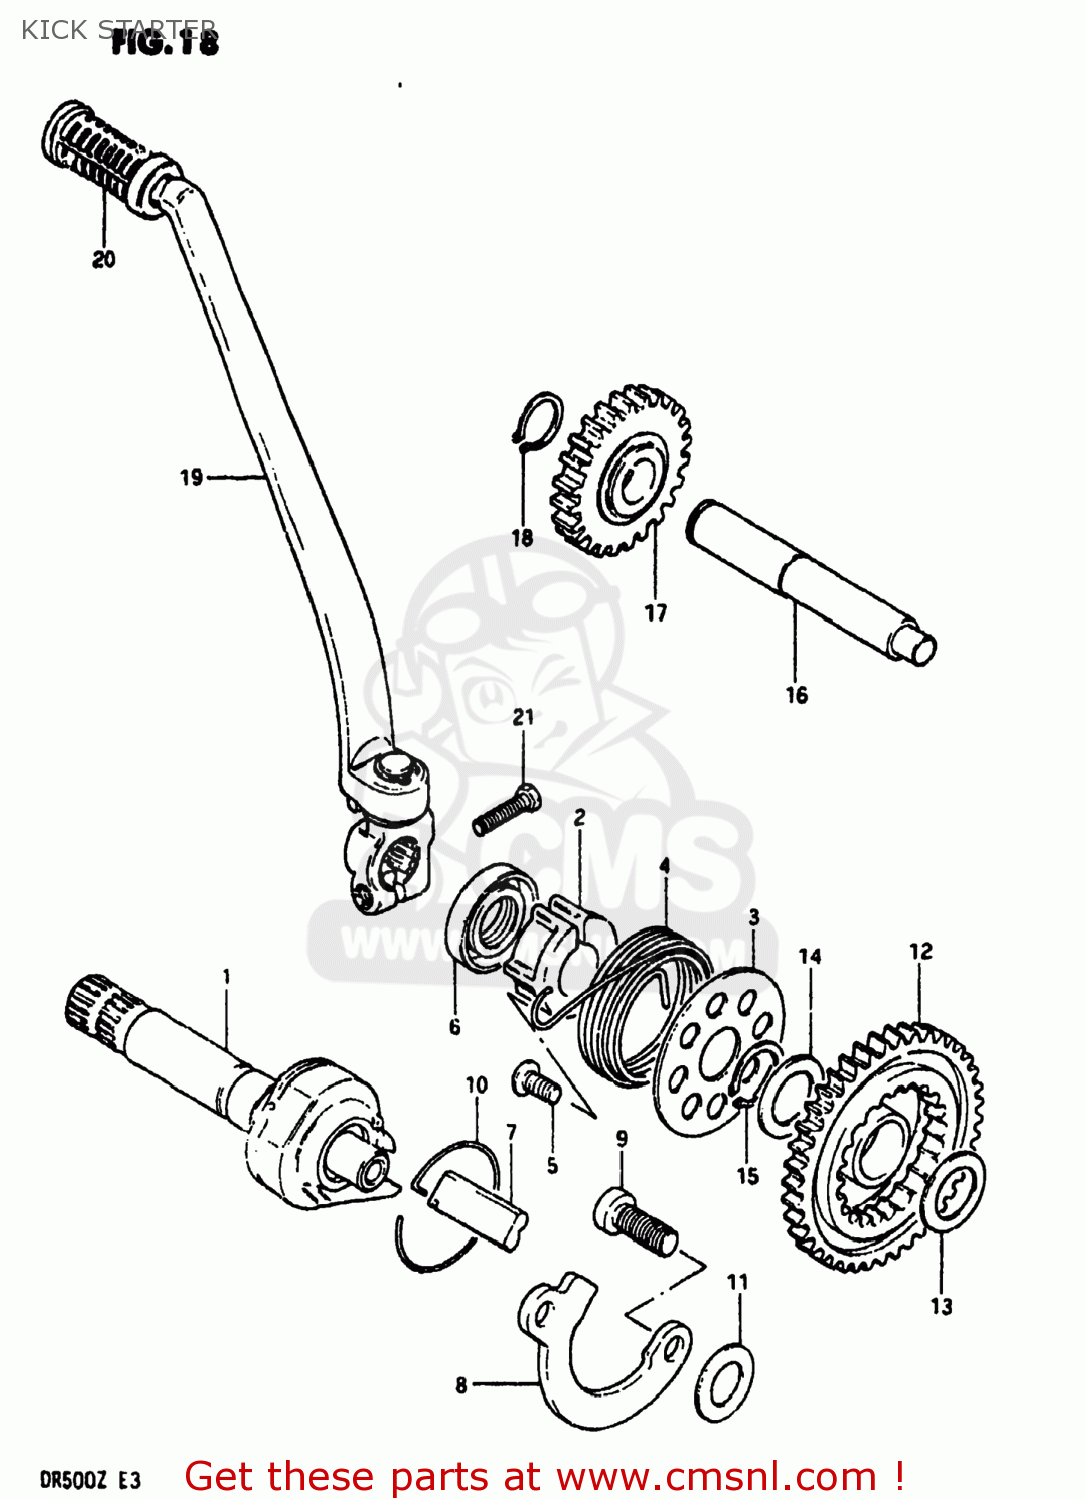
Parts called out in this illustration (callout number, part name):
1	SHAFT,KICK STARTER
2	GUIDE,KICK SHAFT SPRING
3	HOLDER,KICK SHAFT SPRING
4	SPRING
5	SCREW
6	SEAL,OIL(20X37X7)
7	PAWL,KICK STARTER
8	LIFTER,KICK STARTER
9	STOPPER,KICK STARTER
10	SPRING,KICK START PAWL RETURN
11	WASHER
12	GEAR,KICK STARTER DRIIVE
13	WASHER
14	WASHER,THRUST
15	CIRCLIP
16	SHAFT,KICK STARTER IDLE
17	GEAR,KICK STARTER IDLE
18	CIRCLIP
19	LEVER ASSEMBLY,KICK STARTER
20	RUBBER,KICK STARTER PEDAL
21	BOLT(8X25)
